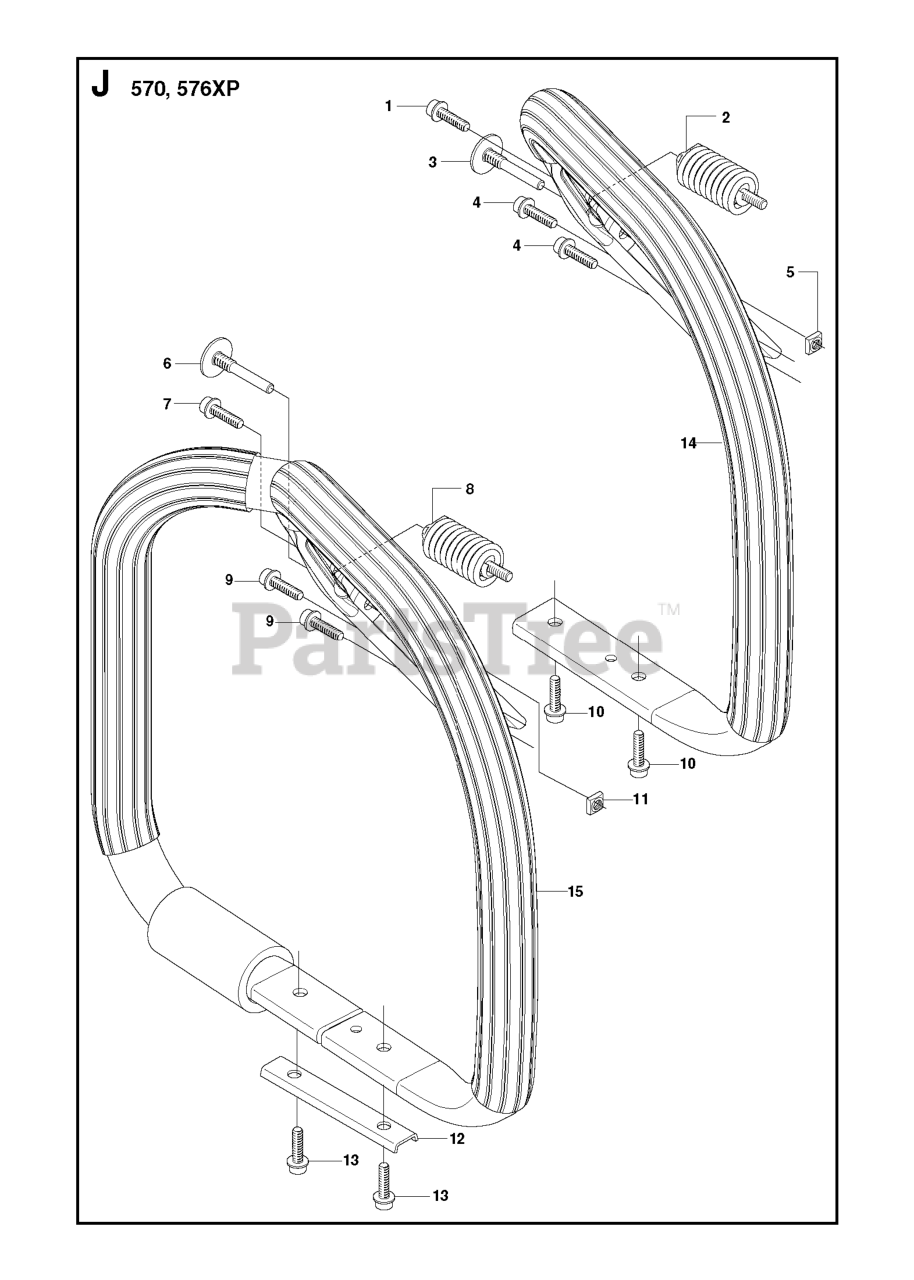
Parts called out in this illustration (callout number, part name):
2	ANTIVIBE MOUNT
8	ANTIVIBE MOUNT
14	FRONT HANDLE ASSY
14	%FRONT HANDLE
15	HANDLE
